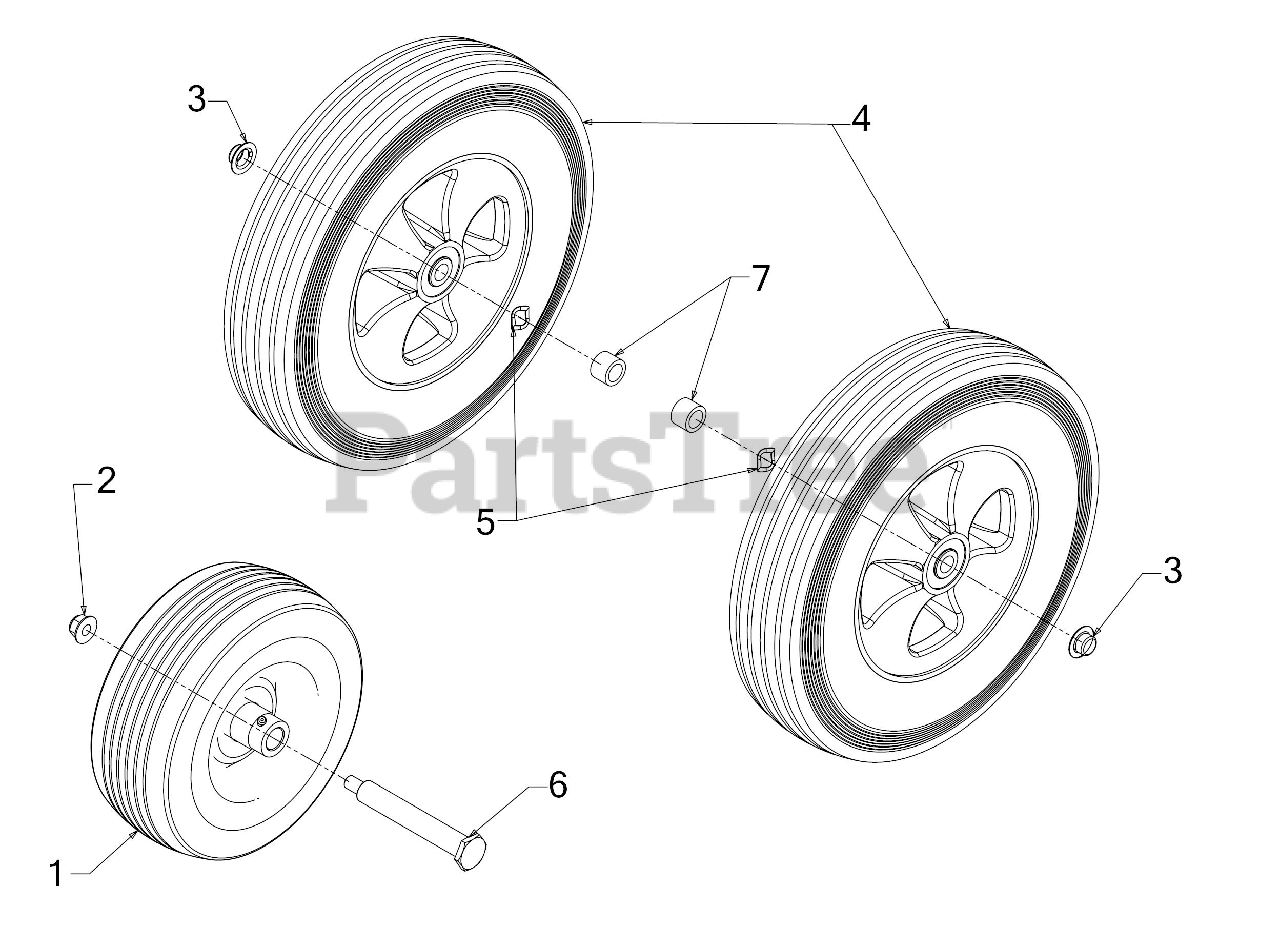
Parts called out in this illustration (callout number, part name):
1	WHEEL-8.0 x 3.0 SOLID (CUB BEIGE)
1	FLANGE BUSHING
1	COMPLETE WHEEL
4	WHEEL-12X3 BB SEMI PNEU BEIGE
5	WAVE WASHER
6	SHOULDER SCREW .625 x 3.94
7	SPACER-.525 x .775 x .560
